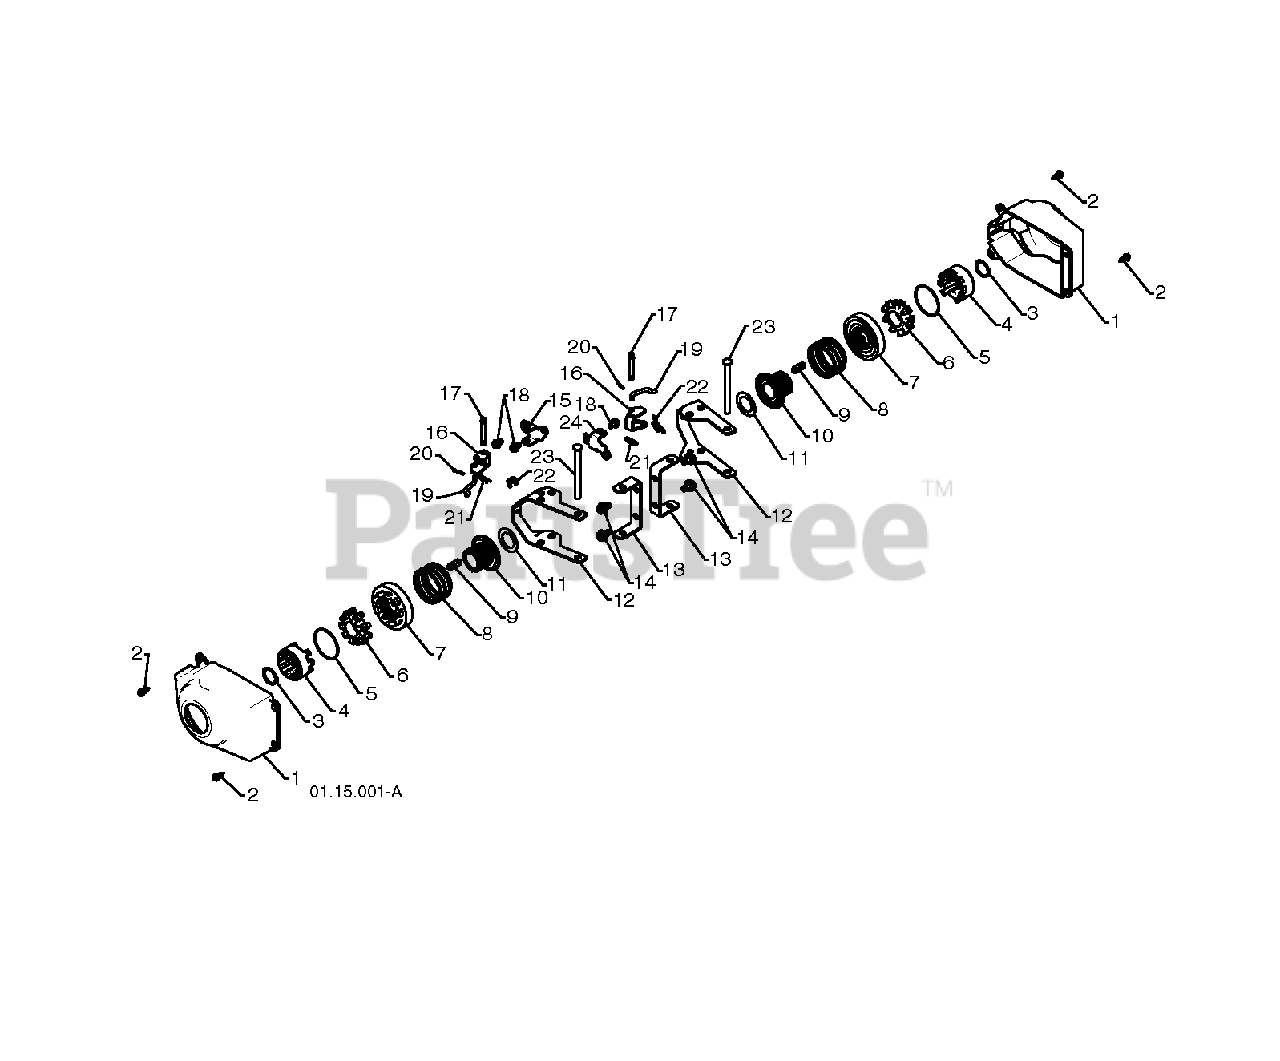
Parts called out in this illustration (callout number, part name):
1	COVER, POWER STEERING
2	SCREW, HEX HEAD, TAPPING
4	DRIVER WHEEL
5	RING, WIRE RETAINER
7	SLIDE.CLUTCH
8	SPRING, CLUTCH SLIDE
9	KEY, SQUARE 1/4 X .875
10	LOBE.AXLE
11	WASHER TRUST 1"
12	YOKE.PNT.WELDMENT.STEE
13	BRACKET
15	BRKT.STEER.PIVOT.RH
16	BELLCRANK.STEER
17	PIN, STEERING BELLCRANK
19	LINK.STEER.YOKE
20	RETAINER CLIP
21	RETAINER CLIP PM
23	PIN, STEERING LEVER
24	CONTROL SHAFT
